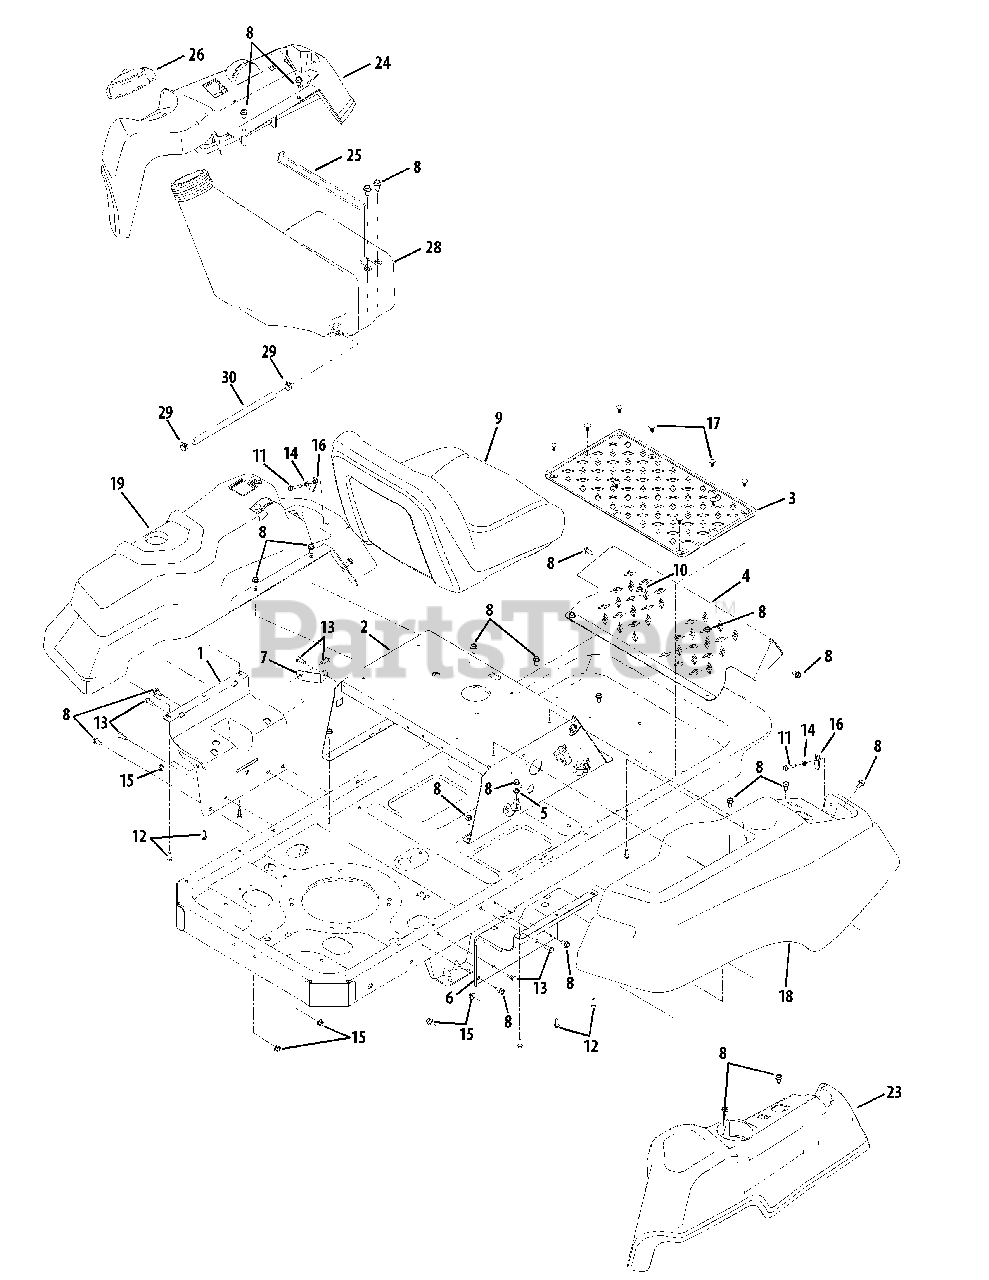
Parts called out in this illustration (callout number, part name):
1	Console Mtg. Brkt. LH
3	Foot Pat
4	Foot Rest Bracket
5	Ext. Tooth Washer, 3/8
6	Console Mtg. Brkt. RH
7	Fuel Tank Support Bracket
8	Hex Washer Screw 5/16-18 x .75
9	High Back Seat
10	Self-tapping Screw 5/16-18 x .625
11	Hex Wash HD Bolt 1/4-20 x 1.50" Lg.
12	Hex Tapp Scr 1/4 x .75" Lg.
13	Hex Screw 5/16-18 x .75
14	Hex Jam Nut 1/4-20
15	Hex L-Flg.Nut 5/16-18 Gr. F, Nylon
16	U-Type Speed Nut 1/4-20
17	Ratchet Clip
18	Console, RH (Cub Cadet)
19	Console, LH (Cub Cadet)
25	Tank Mtg. Wire
26	Fuel Cap
28	Fuel Tank 3 gal.
30	Hose, Fuel Low Permeation (B&S)
